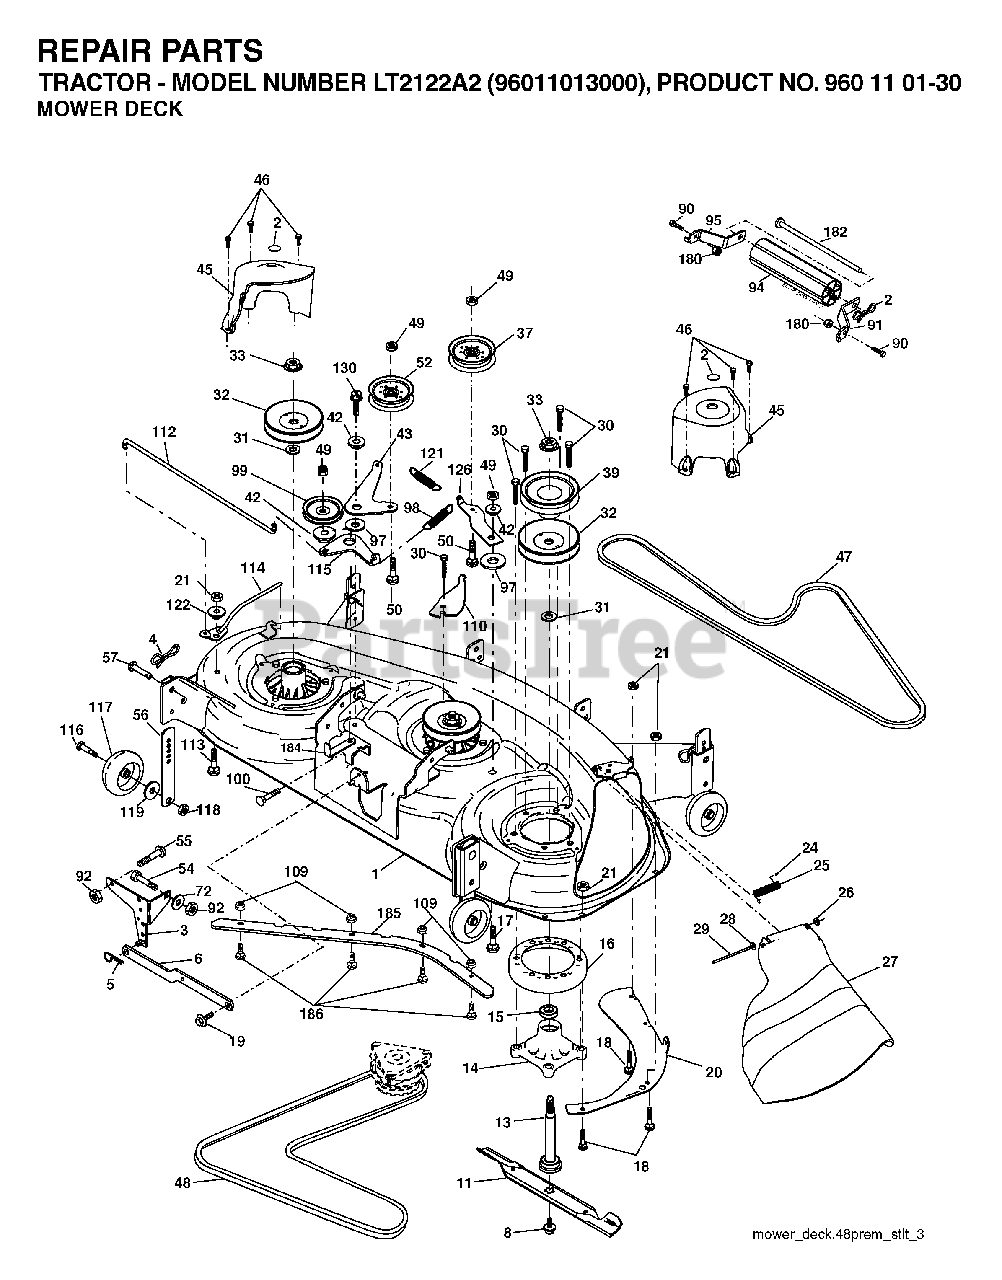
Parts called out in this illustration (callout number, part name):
1	DECK WELDMENT
2	PIN.COTTER.7/16.BOW TI
3	BRKT ASM SWAY BAR
4	PIN.COTTER.5/16.BOW TI
5	RETAINER-SPRNG RB
6	BAR SWAY DECK
8	BOLT 7/16 ASM BLADE
11	48" HI-LIFT BLADE
13	SHAFT ASM W/LOWER BEARING
14	HOUSING, MANDREL 48"
16	STRIPPER, MWR ROUND
17	BOLT
18	BOLT
19	BOLT SHD 5/16-18
20	BAFFLE, VORTEX MWR
21	LOCKNUT
24	CAP-SLEEVE LT
25	SPRING, TORSION
26	NUT PUSH M
27	DEFLECTOR SUBS TO 532 180655
28	WASHER
29	ROD.HINGE
30	SCREW, WASHER HEAD
31	WASHER.SPACER.MANDREL
32	PULLEY/MANDREL
33	NUT.FLANGE.LOCK.TOP
37	PULLEY.IDLER.48"PRIMARY
39	PULLEY.IDLER.DRIVEN
42	SPACER.RETAINER.MOWER
43	ARM, IDLER SECONDARY
45	COVER.MANDREL.DECK.48"
46	SCREW.1/4-20X5/8
47	V-BELT, 48"SECONDARY
48	V-BELT PRIMARY 48"
49	NUT LOCK FLG 3/8-16 UNC
50	BOLT.3/8-16X1.50
52	PULLEY.IDLER.FLAT.UNPLATED
55	BOLT D
56	BAR.ADJUST.WHEEL.ANTI.SCALP.BL
57	RIVET.PIN.HEAD.YELLOW
72	WASHER
90	BOLT RB
91	BRKT.NOSEROLLER.RH.48"
92	NUT
94	NOSE ROLLER 48"
95	BRKT.NOSEROLLER.LH.48"
98	SPRING PRIMARY DRIVE
99	PULLEY.V.IDLER
100	BOLT
109	NUT.CROWNLOCK.1/4
110	ARM, SPRING SECONDARY
112	LEVER, TENSION RELIEF LINK
114	LEVER ASM, TENSION RELIEF
115	ARM, SPRING TENSION RELIEF
116	BOLT.SHOULDER.3/8-16X3-5/8
117	WHEEL. GUAGE RALLY
118	LOCKNUT
119	WASHER
121	SPRING SECONDARY DR
122	BUSHING, PIVOT TENSION RELIEF
126	ARM, IDLER PRIMARY DECK
130	SCREW 3/8-16X1
180	NUT.71038.31-18.HEX.NYLOCK
182	ROD.ROLLER.NOSE.NARROW.48"
184	KEEPER BELT IDLER PLATED
186	BOLT
